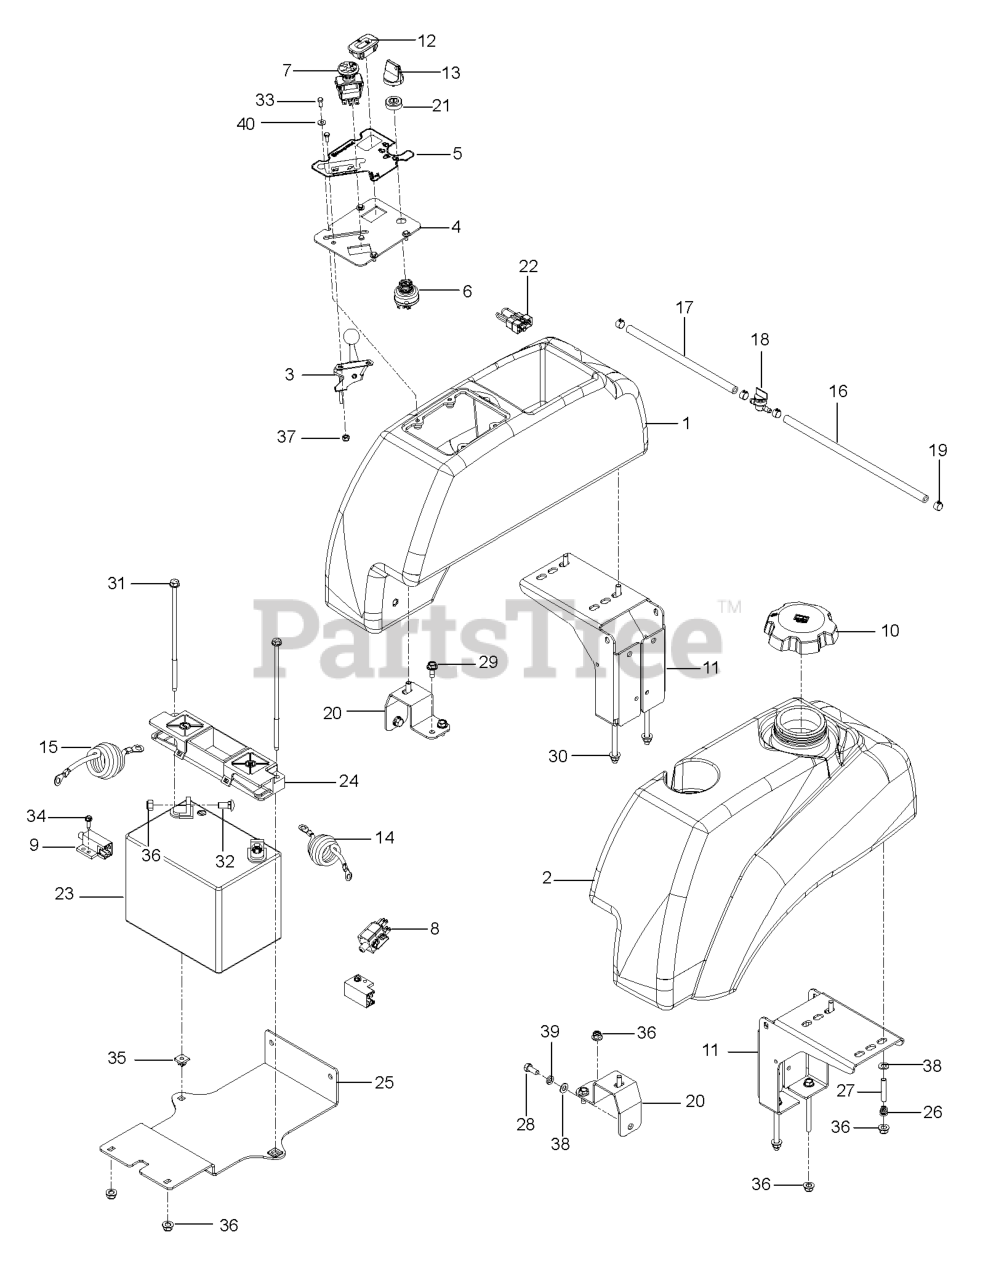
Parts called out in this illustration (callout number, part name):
1	FENDER CONSOLE
2	LEFT TANK W/CUP HOLDER
3	THROTTLE CABLE
4	RP.PLATE, CONSOLE, BLK
5	DECAL, CONSOLE
6	SWITCH, IGNITION, INDAK
7	RP SWITCH.PTO.TERMINAL.STD.RED
8	SWITCH, BRAKE 3P
9	SWITCH, INTERLOCK
10	FUEL CAP, HTC
11	SUPPORT, TANK, BLK
12	HOUR METER
13	KEY, IGNITION
14	NUT 10-24 NYLOC
15	HCS 5/16C X 3/4
16	FUEL LINE 18"
17	FUEL LINE 13"
18	FUEL VALVE
19	HOSE CLAMP
20	MOUNT, TANK, ZT BLK
21	CAP IGNITION NUT
22	PLUG, TIMER
23	BATTERY, 12 V 330 AMP
24	BATTERY HOLD DOWN
25	PLATE, BATTERY, BLACK
27	STUD, 5/16C
28	BOLT.FIN.HEX.5/16-18X3/4
29	RP BLT 5/16-18 X 1 THRD FORM D
30	HHFS 5/16-18 X 3 3/4
31	BOLT - 1/4-20 X 7.5
32	BOLT 5/16C X 3/4" CARRIAGE
33	SCREW
34	SCREW #10-24 X 5/8
35	PUSH NUT-NYLON
36	5/16-18 NYLOC FLANGE NUT
37	NUT 10-24 NYLOC
38	FLAT WASHER 5/16 SAE
39	WASHER.LOCK.HVY.HLCL.SPR.5/16
40	WASHER #10
